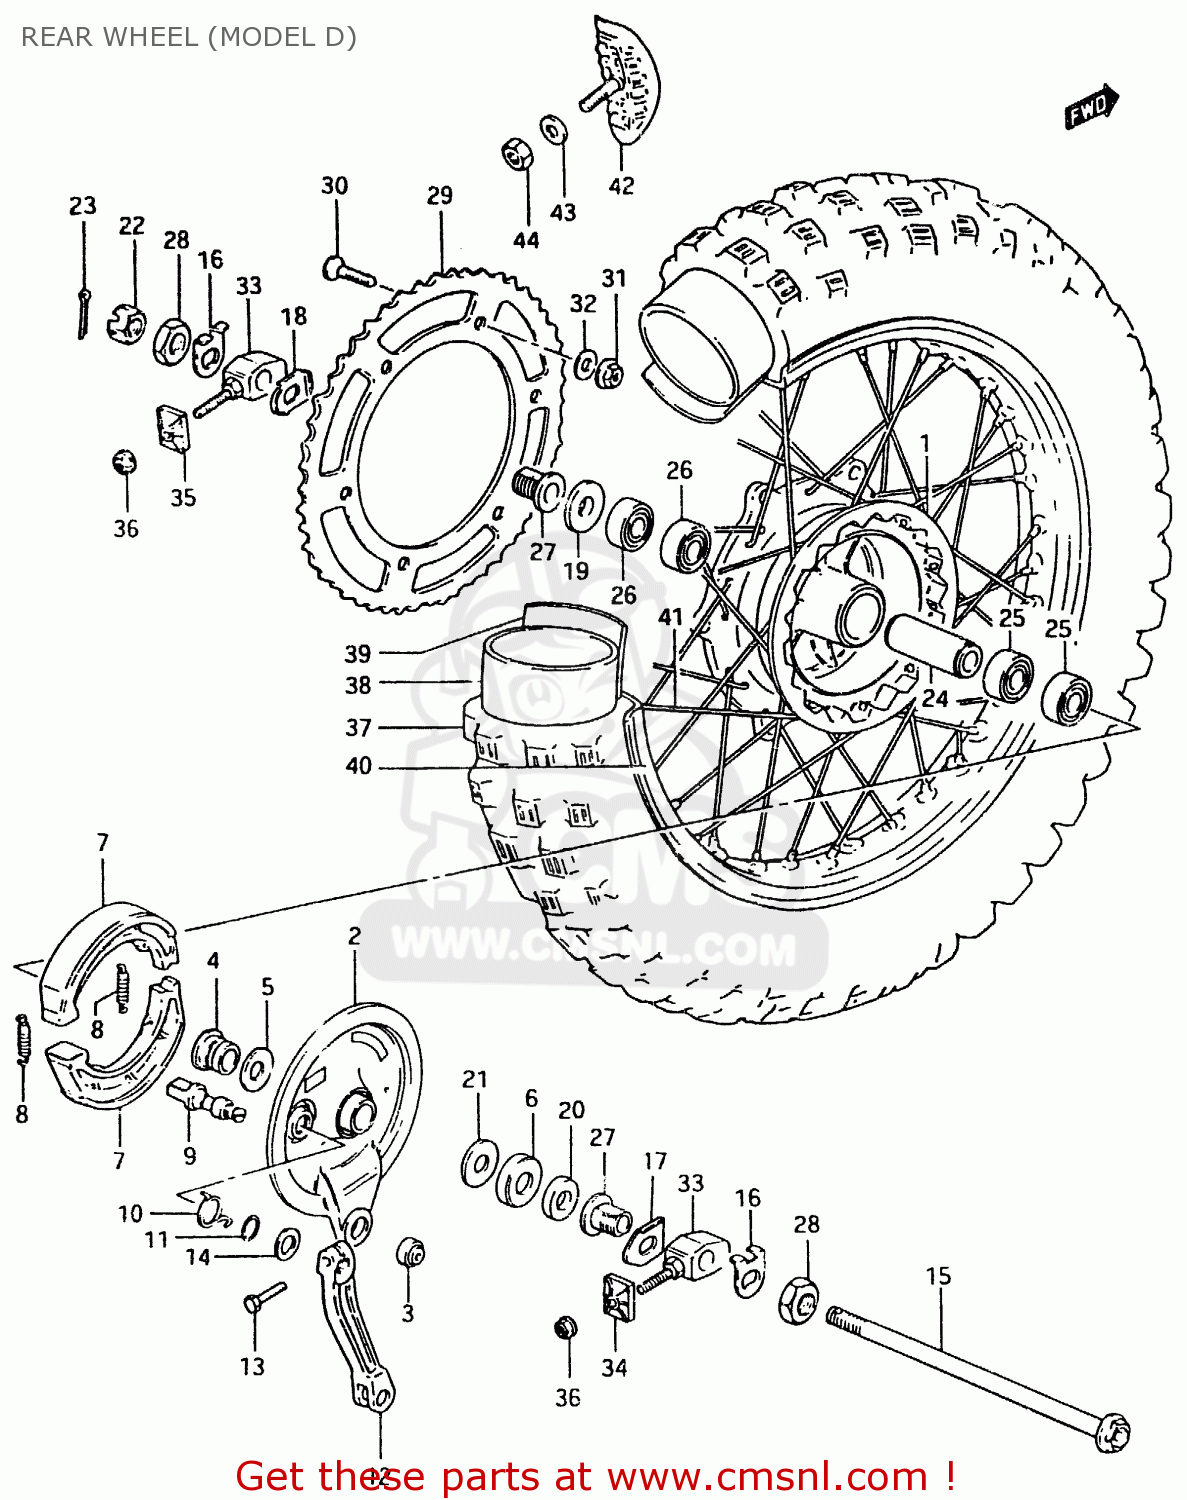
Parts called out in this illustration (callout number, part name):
1	DRUM,REAR HUB
2	PANEL SET,REAR HUB
3	SPHERICAL BRNG,TORQUE LINK
4	SPACER,RR BRAKE ANCHOR PANEL
5	SEAL,OIL(20X27X5)
6	CVR,RR BRAKE AHR PNL DUST SEAL
7	SHOE,BRAKE
8	SPRING
9	CAM,FR BRAKE
10	SPRING
11	O RING(D:2.5,ID:11.4)
12	LEVER,RR BRAKE CAM
13	BOLT
14	WASHER(12.5X20X1)
15	AXLE,REAR
16	WASHER,CHAIN ADJUSTER GUIDE
17	PLATE,CHAIN ADJUSTER,RIGHT
18	PLATE,CHAIN ADJUSTER,LEFT
19	SPACER,REAR AXLE,LEFT
20	SPACER,REAR AXLE,RIGHT
21	WASHER,THRUST
22	NUT
23	COTTER PIN
24	SPACER,REAR HUB BEARING
25	BEARING
26	BEARING
27	SPACER,CHAIN ADJUSTER
28	NUT
29	SPROCKET,REAR
30	SCREW(8X40)
31	NUT
32	WASHER
33	ADJUSTER,CHAIN
34	PLATE,CHAIN ADJUSTER GEAR
35	PLATE,CHAIN ADJUSTER GEAR
36	NUT
37	TIRE
38	TUBE,INNER
39	PROTECTOR,WHEEL,INNER
40	RIM,REAR WHEEL
41	SPOKE SET,REAR WHEEL
42	STOPPER,BEAD
43	WASHER
44	NUT
